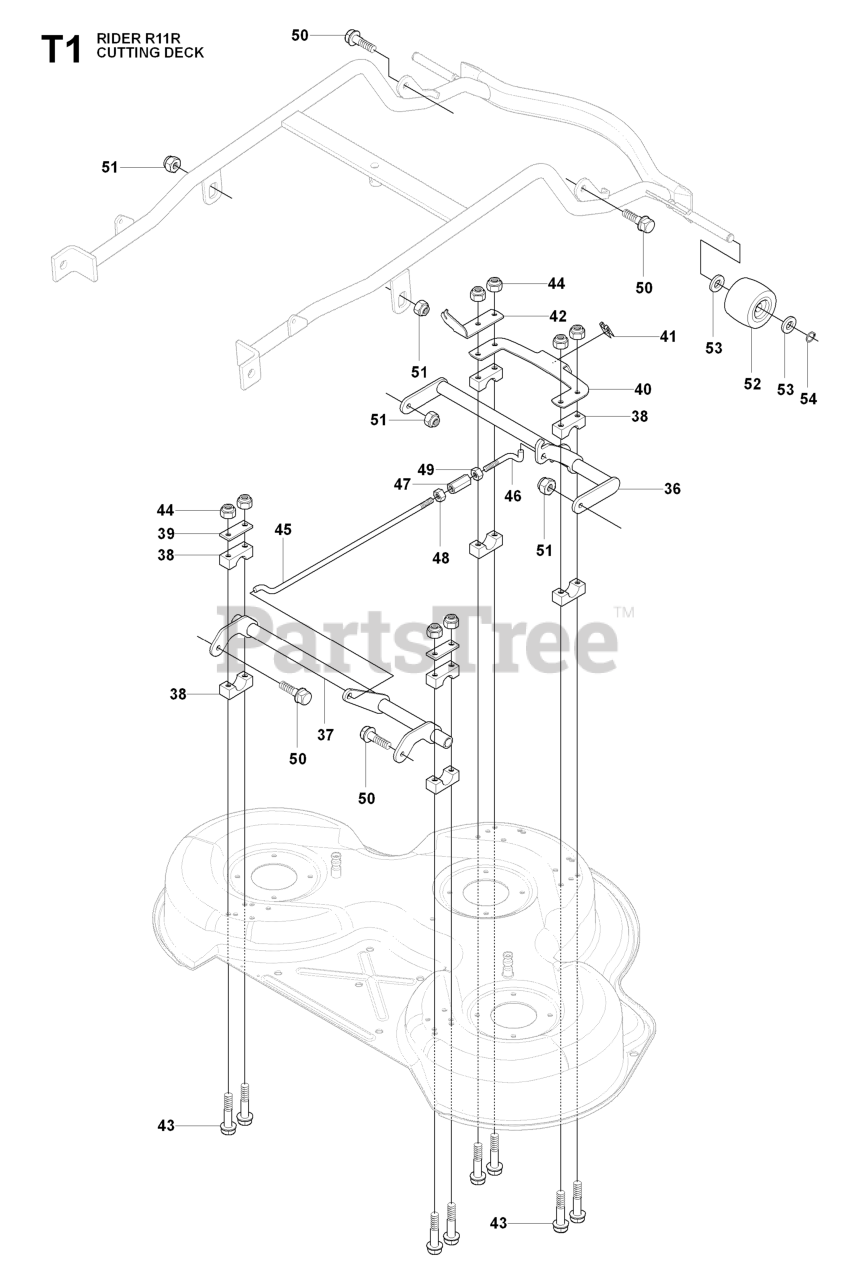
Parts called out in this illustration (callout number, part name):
42	BRACKET HANDLE
44	LOCKNUT M8
49	NUT
51	LOCKNUT M8
52	DECK ROLLER, FRONT
54	RETAINING RING SGA 15
